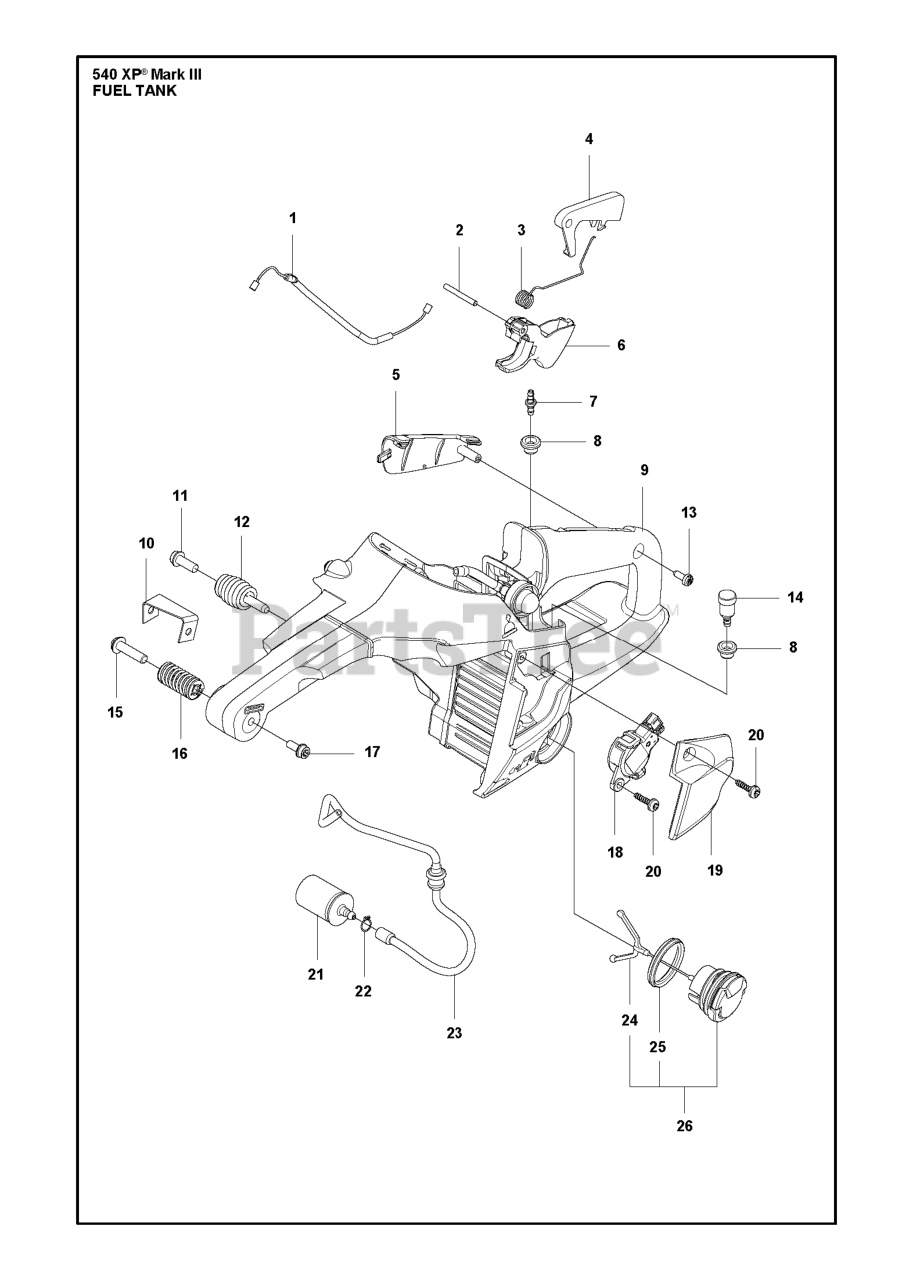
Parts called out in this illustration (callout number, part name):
4	THROTTLE LOCKOUT
5	HANDLE INSERT
11	SCREW ITXSCFM
13	SCREW CITXPANT
15	SCREW
17	SCREW
21	FUEL FILTER
26	TANK CAP ASSY
